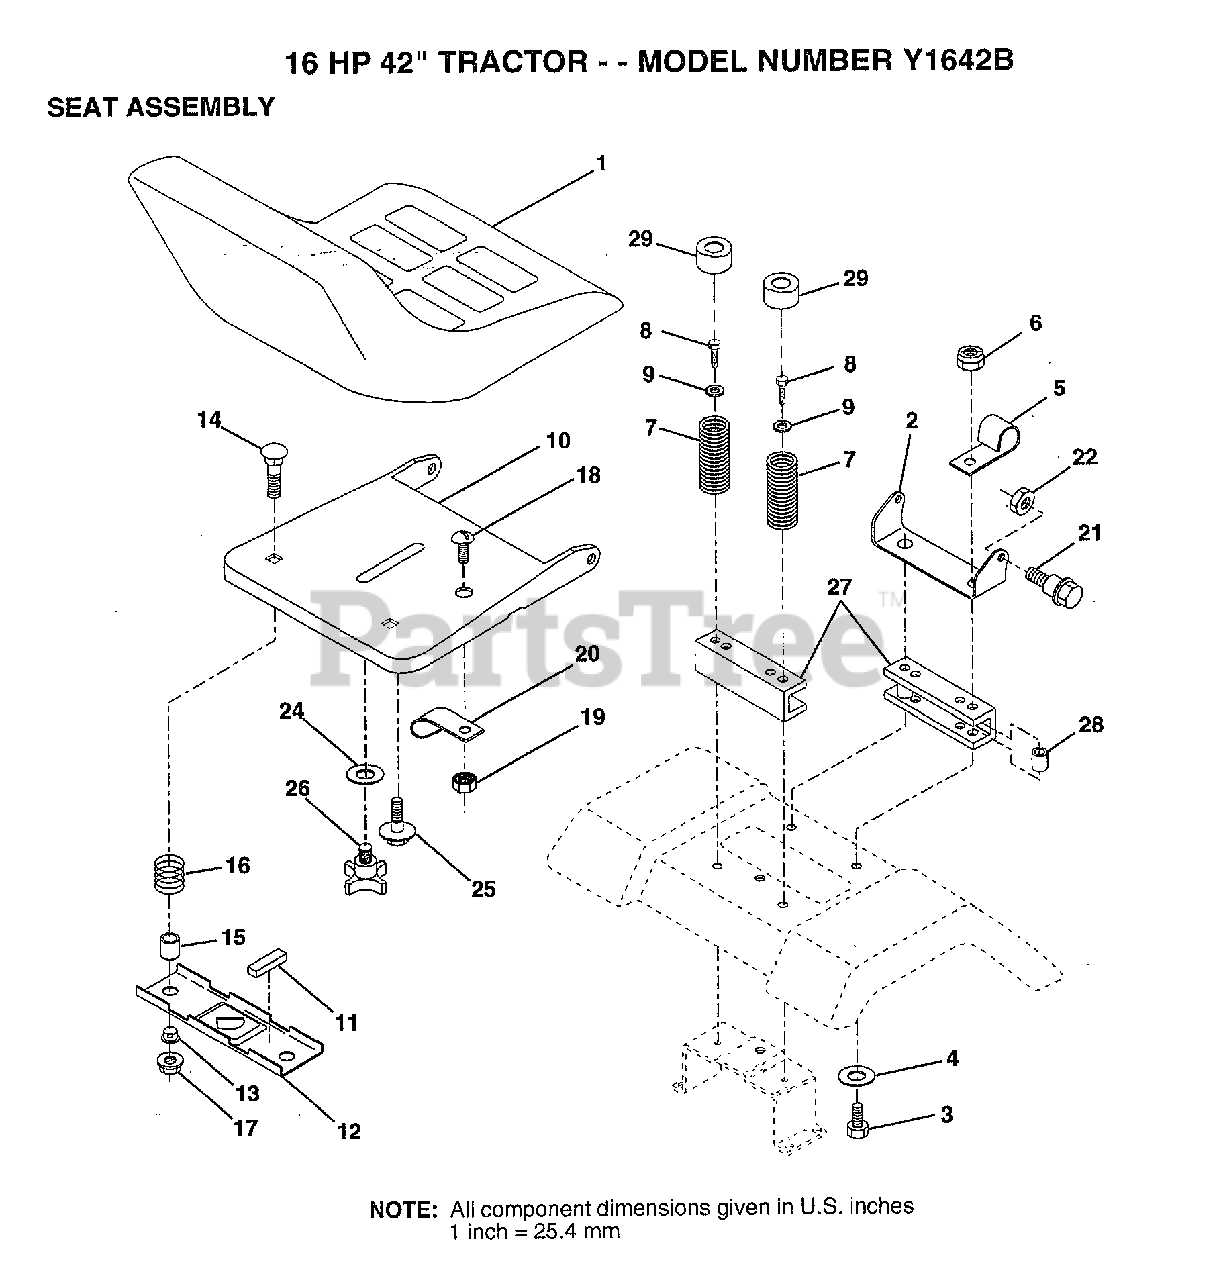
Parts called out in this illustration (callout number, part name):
4	WASHER
5	CLIP T
7	SPRING COMPRESSIO
8	SCREW
9	WASHER
11	STRIP FORM
12	BRKT SWITCH
13	BUSHING
15	SPLIT SPACER
16	SPRING
19	"NUT,KEPS"
24	WASHER
25	"BOLT,SHOULDER"
26	"KNOB 1/2"" YT"
27	SEAT SPACER
28	SPLIT SPACER
29	CAP SPRING
